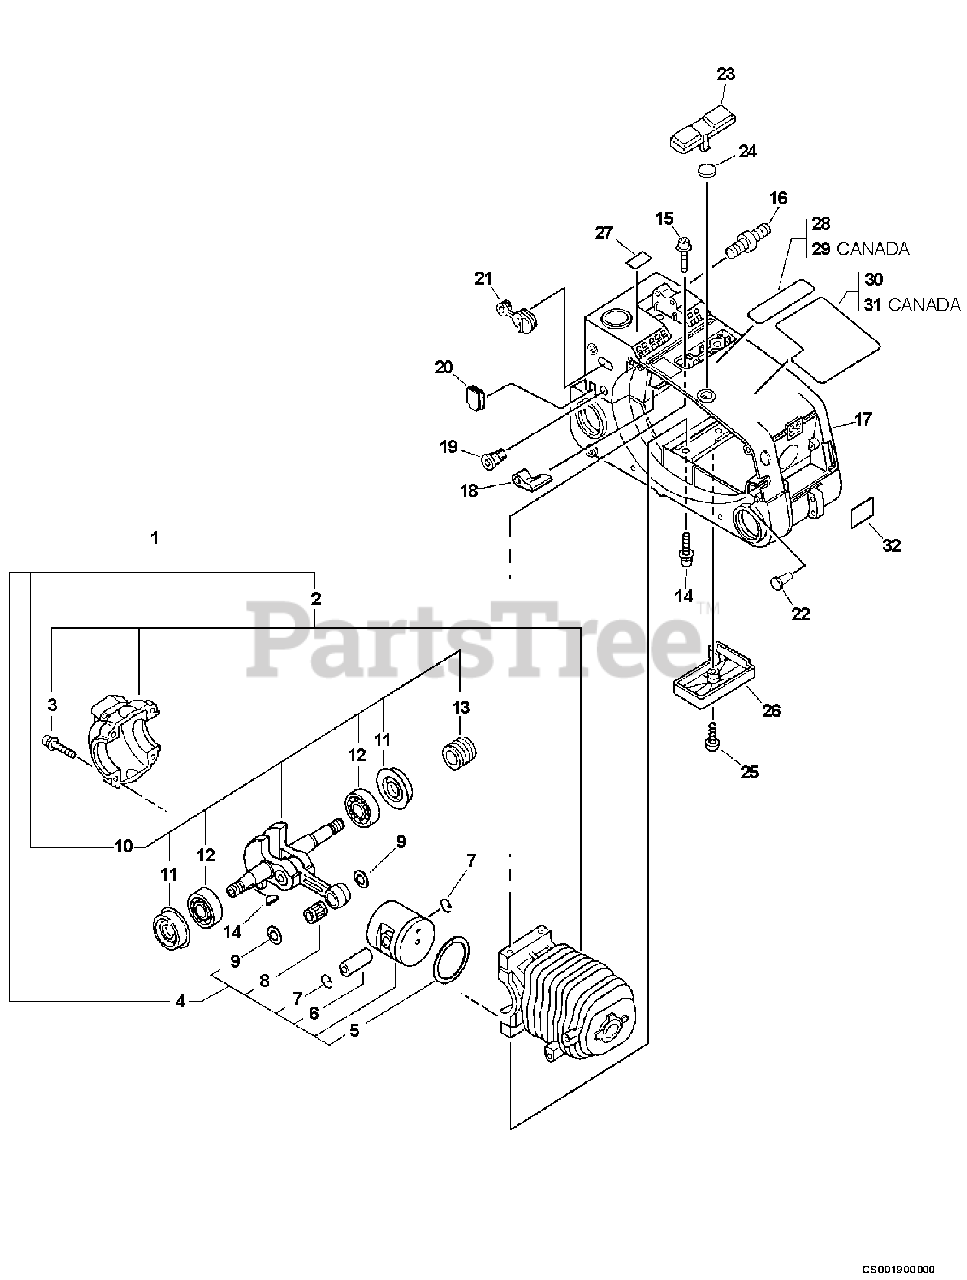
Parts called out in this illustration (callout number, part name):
1	SHORT BLOCK -- SB1052
2	CRANKCASE KIT
3	SCREW - 5X25
4	PISTON KIT
5	RING, PISTON
6	PIN, PISTON
7	RING, RETAINING
8	BEARING, NEEDLE
9	SPACER, PISTON
10	CRANKSHAFT ASSY
11	SEAL, OIL
12	BEARING, BALL - 6201
13	GEAR - WORM
15	SCREW - 5X16
16	STUD, GUIDE BAR
17	COVER, ENGINE - GRAY
22	VENT, TANK
23	COVER - GRAY
25	SCREW - 4X16
26	COVER, BOTTOM - GRAY
27	LABEL - PURGE PUMP
28	LABEL - CAUTION -- SPANISH
29	LABEL - NOISE
30	LABEL - KICK BACK
31	LABEL - KICK BACK
32	LABEL - HOT SURFACE
